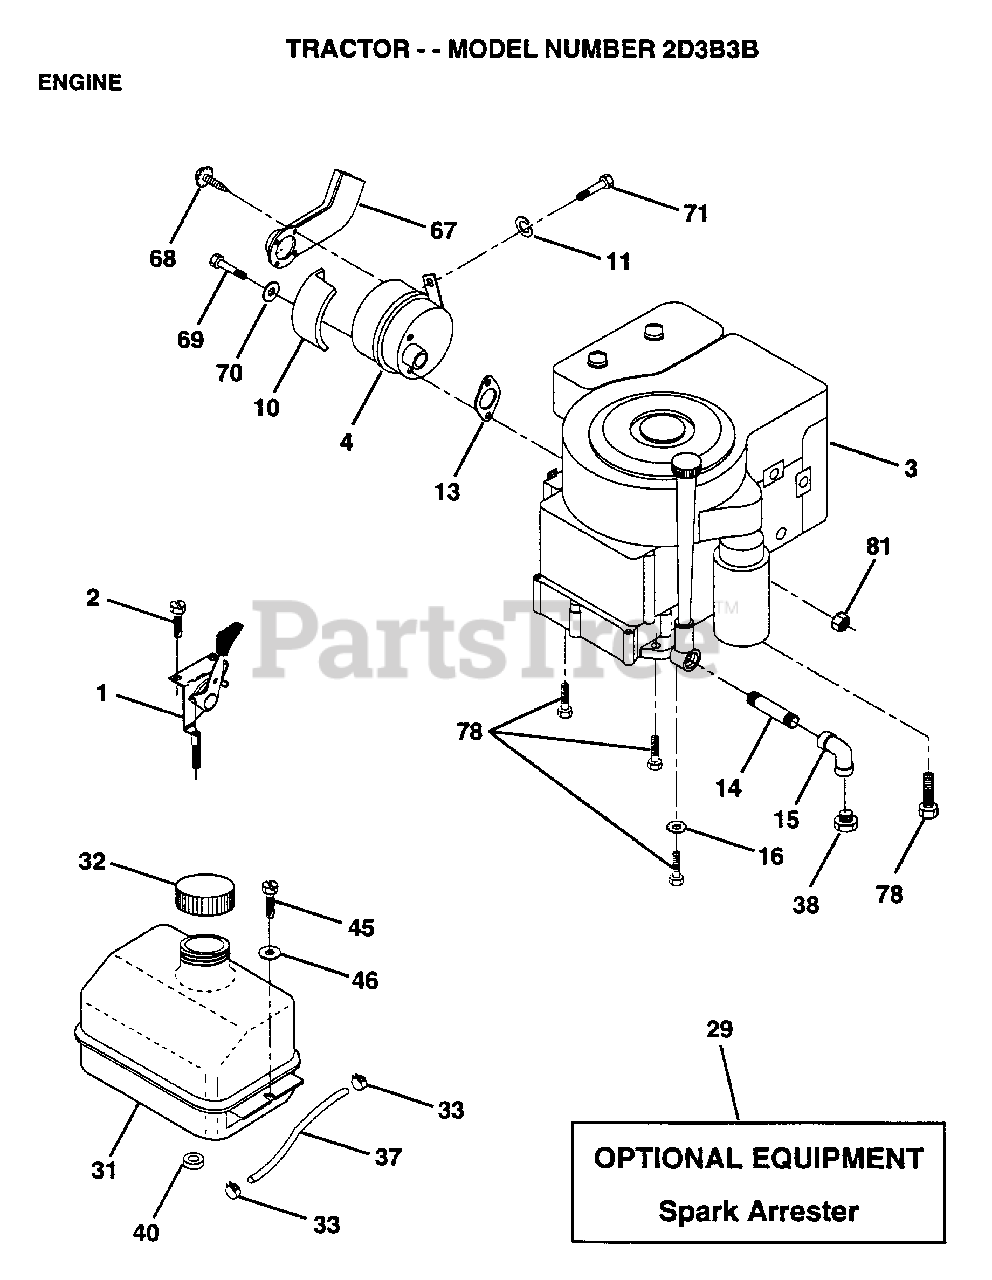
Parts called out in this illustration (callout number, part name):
1	THROTTLE CONTROL
2	SCREW LT
3	ENG B&S 10-12.5HP PWRBLT DC
4	MUFFLER LTV
10	SHIELD HEAT LTV
11	LOCKWASHER
14	PIPE NIPPLE
15	ELBOW
16	LOCKWASHER
31	TANK.FUEL.LT.
32	CAP ASM FUEL
33	HOSE CLAMP
37	LINE FUEL
45	SCREW HEX CRT
46	WASHER
67	DEFLECTOR MUFFLER
69	"BOLT,HEX"
70	WASHER T
71	BOLT HXHD FIN
78	SCREW
81	NUT
